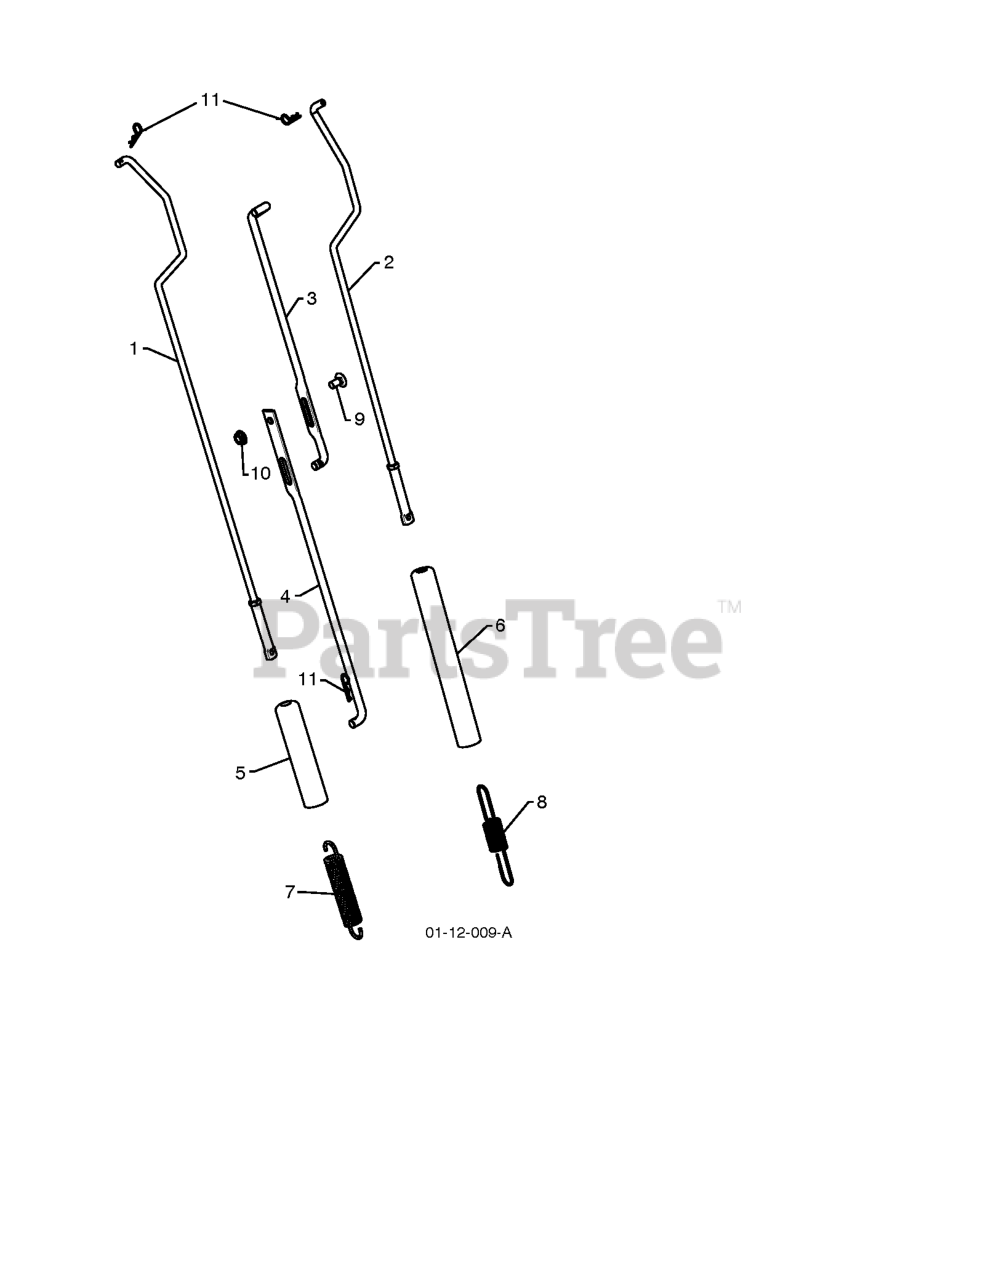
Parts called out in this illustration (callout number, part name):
1	ROD.ASM.TRACTION
2	TRACTION ROD ASSY.
3	ROD.SHIFTER.TOP.HYD.SNOW
4	ROD, LOWER, SPEED CONTROL
5	SLEEVE, SPRING
6	SLEEVE, SPRING
7	SPRING, AUGER CONTROL
8	SPRING, TRACTION DRIVE
9	BOLT
10	NUT.FLANGE.5/16
11	SPRING RETAINER
